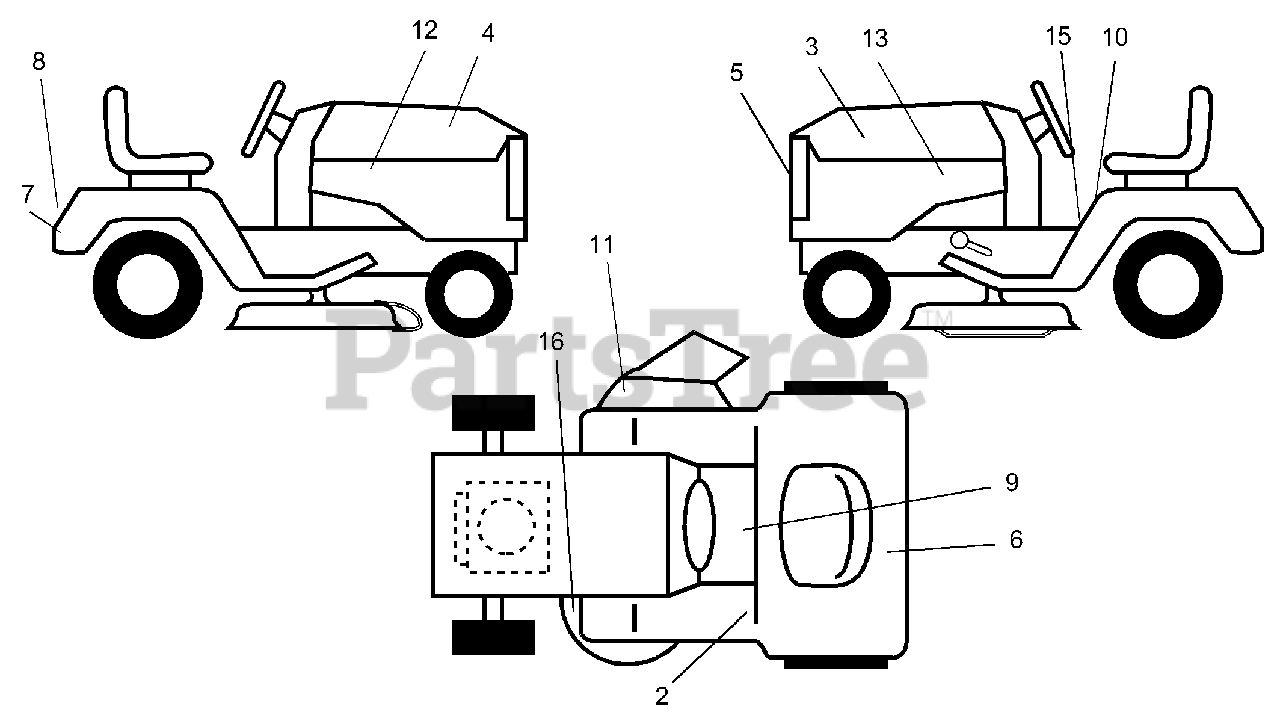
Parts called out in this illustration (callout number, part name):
2	Decal Indicator Height
3	Decal, Hood, L.H.
4	Decal, Hood, R.H.
5	Decal, Logo, Grill
6	Decal, Caution Battery
7	Decal, Drawbar
8	Decal, Logo, Fender
9	Decal, Cold Start
10	Decal, Fender, Caution
11	Decal, Warning, Multi-Language
12	Decal, Hood, Insert, R.H.
13	Decal, Hood, Insert, L.H.
15	Decal, Instruction, Operating
16	Decal, V-Belt Schematic
